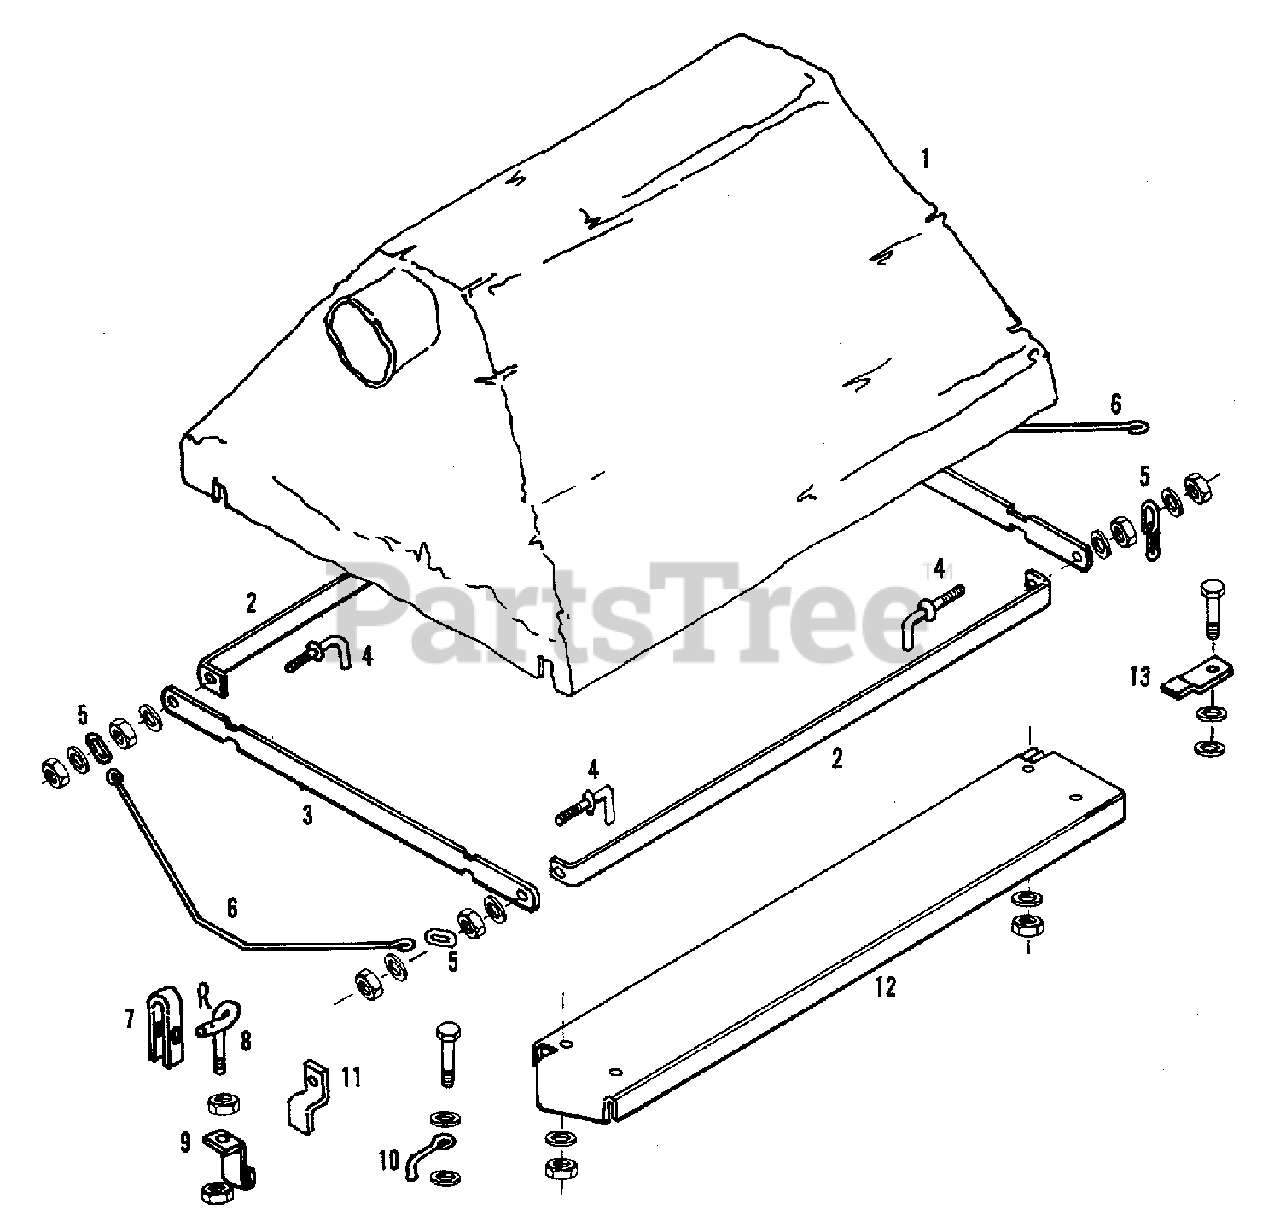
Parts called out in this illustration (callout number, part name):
1	COVER, Cart
2	BAR, Reinforce Side
3	BAR, Reinforce End
4	WASHER, 3/8
4	NUT, 3/8NC
5	LINK, Repair
5	NUT, 3/8NC, Lock
8	ROD, Latch
9	PIN, 1/8 x 1, Cotter
9	NUT, 3/8NC, Lock
10	STOP, Belt
12	PANEL, Side
13	WASHER, Special
13	WASHER, 5/16
13	CAPSCREW, 5/16 x 3/4
13	NUT, 5/16NC, Lock
13	CAPSCREW, 3/8NC x 1-1/4
